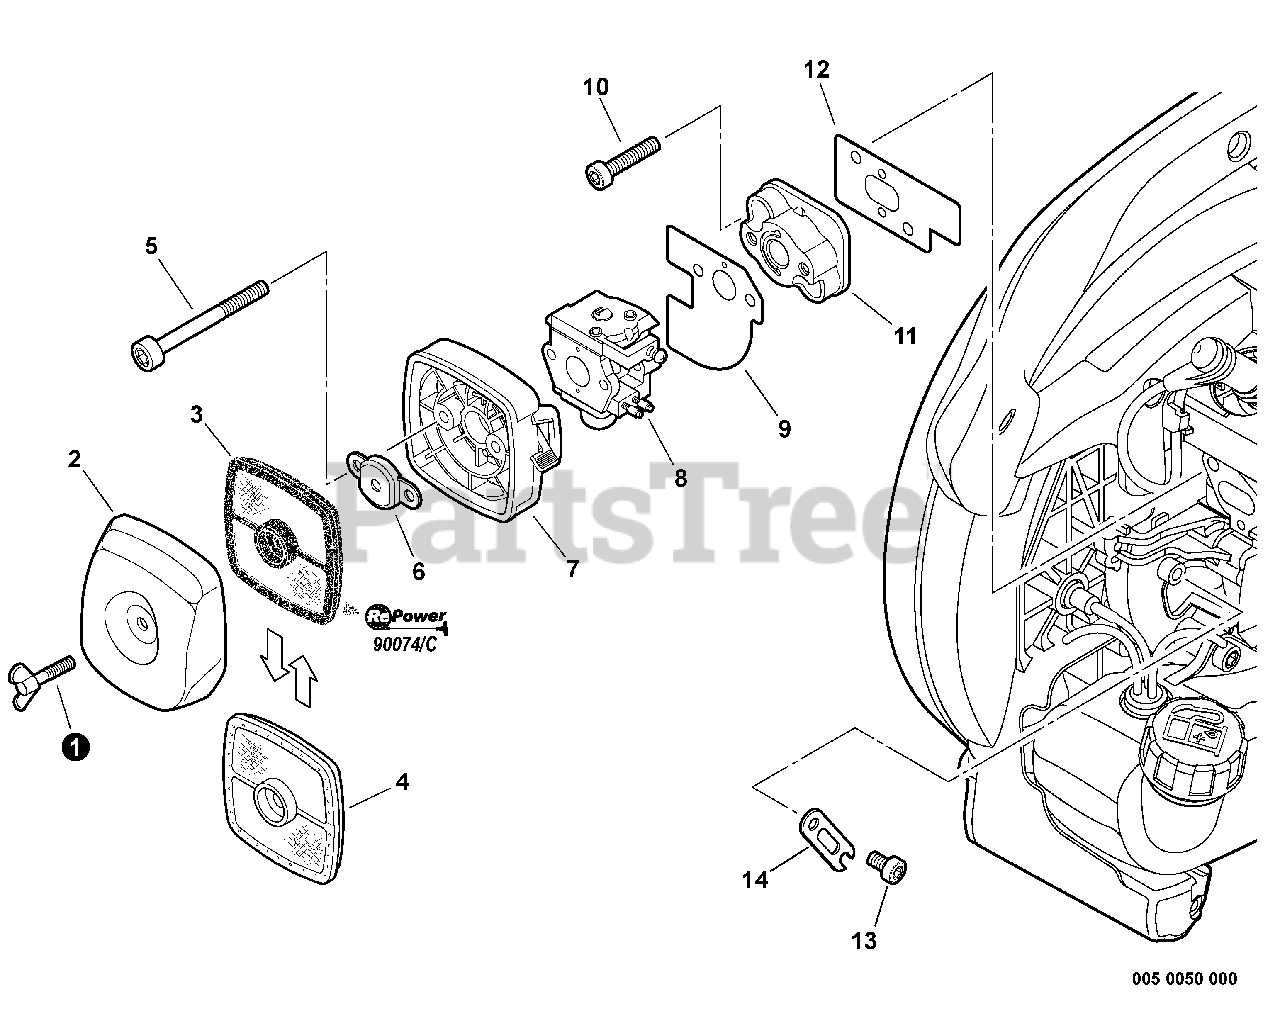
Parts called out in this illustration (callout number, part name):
1	THUMBSCREW
2	COVER, AIR FILTER - BLACK
3	FILTER, AIR - DOUBLE LAYER
4	FILTER, AIR - SINGLE LAYER
5	SCREW - 5X65
6	PLATE, PREVENT
7	CASE, AIR FILTER - BLACK
8	CARBURETOR
9	GASKET, INTAKE
10	SCREW - 5X25
11	INSULATOR, INTAKE
12	GASKET, INTAKE
13	SCREW - 5X8
15	RePower TUNE-UP KIT
